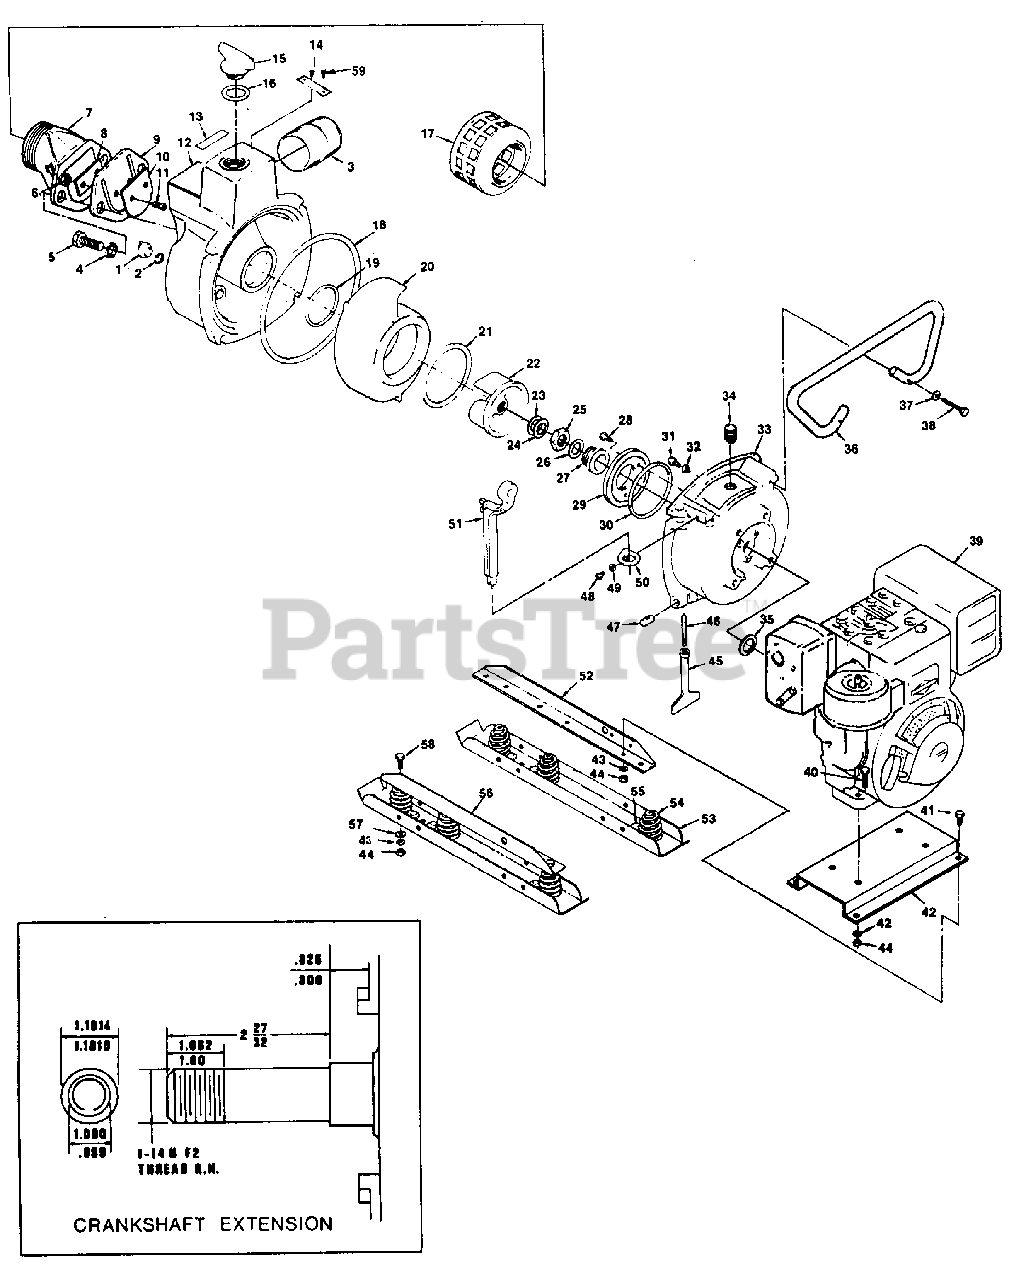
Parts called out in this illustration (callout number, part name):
1	PLUG- Drain
4	WASHER- Lock 1/2"
5	SCREW-1/2-13 x 1 1/4
6	NUT- Hex 10-32
7	FITTING- Suction std. thread
8	PLATE- Small
10	PLATE- Large
11	SCREW-10-32 x 1/2
12	HOUSING- End
14	PLATE- Warning
15	PLUG- Wing
16	GASKET- Wing nut plug
17	STRAINER- (1" inch openings)
18	GASKET- Pump body large
19	GASKET- End plate small
20	HOUSING- Impeller
21	GASKET- Impeller housing
22	IMPELLER
23	SHIM- (.032") impeller
24	SHIM- (.015") impeller
25	NUT- Impeller
26	SHIM- (.010") Seal spring pressure
27	SEAL ASSEMBLY- Pump
28	SCREW- Hex hd. 1/4-20 x 5/8
29	PLATE- Wear
30	"O" RING
31	SCREW- Hex hd., 3/8-16 x 1 1/4
32	WASHER- Sealing
33	BODY- Pump
34	SCREW- Set hex soc. 5/8-11 x 3/4
35	SLINGER
36	HANDLE- Carrying
37	WASHER- Flat 3/8
38	SCREW- Hex hd 3/8-16 x 1 3/4
40	SCREW- Hex hd. 5/16-18 x 1 3/4
41	SCREW- Hex hd. 5/16-18 x 3/4
42	BRACKET- Pump engine
43	WASHER- Lock (5/16)
44	NUT- Hex 5/16-18
45	HANDLE- Disconnect
46	STUD- Handle
47	PIVOT- Handle
48	SCREW- Hex hd. 1/4-20 x 3/8
49	WASHER- Flat 1/4
50	BRACKET- Spanner wrench
51	WRENCH- Spanner
52	ANGLE- Base (right)
54	Spring- Foot
56	ANGLE- Base (left)
57	WASHER- Flat 5/16
58	SCREW- Hex hd., 5/16-18 x 1
59	TACK- Metal
